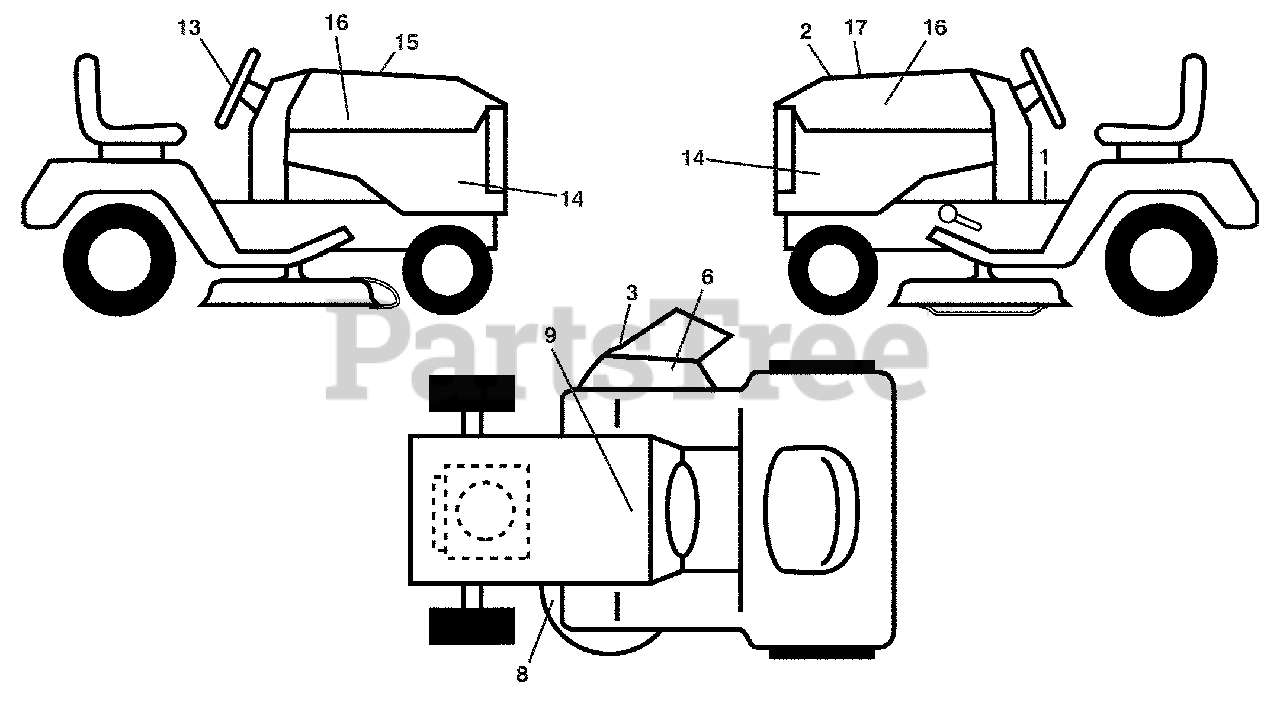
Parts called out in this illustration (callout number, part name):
1	Decal, Operator's
2	Decal, Hood Insert
3	Decal, Warning
6	Decal, "B"
8	Decal, Mower Sch.
9	Decal, Battery Dnge/Poi
13	Decal, Steering Whl
14	Decal, Panel Side
15	Decal, Cust. Resp.
16	Decal, Hood Logo
17	Decal, Replacement
